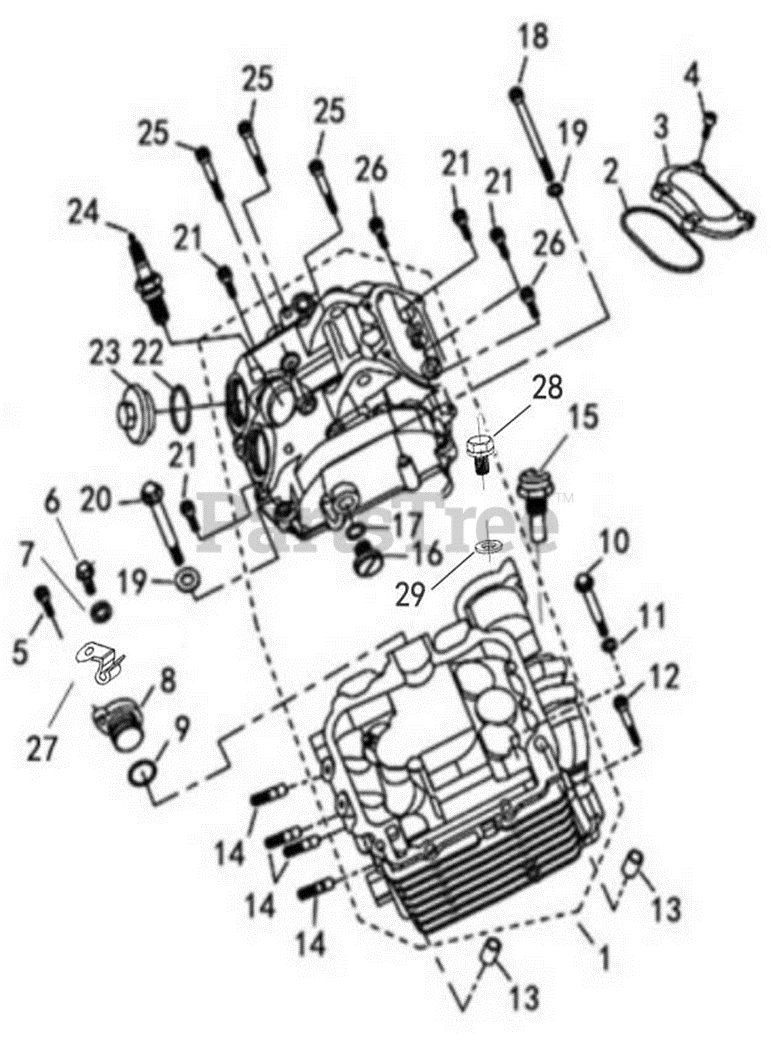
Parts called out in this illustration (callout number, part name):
1	CYLINDER HEAD (BARE)
2	O-RING 71.5X3
3	INTAKE VALVE COVER
4	HEX HEAD CAP SCREWM6X20
5	HEX HEAD CAP SCREWM6X20
6	HEX FLANGE BOLT M6X12
7	ALUMINUM WASHER 6X12X1.5
8	CAMSHAFT END COVER
9	O-RING 18 x 2.4
10	CYLINDER BOLTS M9X109
11	WASHER 10X19X2
12	HEX HEAD CAP SCREW M6X50
13	DOWEL PIN 10X16
14	STUD M8X45
15	3 WIRE TEMP SENSOR
16	SMALL PEEP HOLE COVER
17	O-RING 13.4X2.35
18	HEX HEAD CAP SCREW M6X130
19	ALUMINUM WASHER 6X12X2
20	HEX HEAD CAP SCREWM6X115
21	HEX HEAD CAP SCREW M6X25
22	O-RING 32.7X3.1
23	EXHAUST VALVE COVER
24	SPARK PLUG NGK UV
25	HEX HEAD CAP SCREW M6X55
26	HEX HEAD CAP SCREW M6X40
27	WIRE CLAMP
28	HEX FLANGE M12-1.5:15
29	FLAT WASHER
